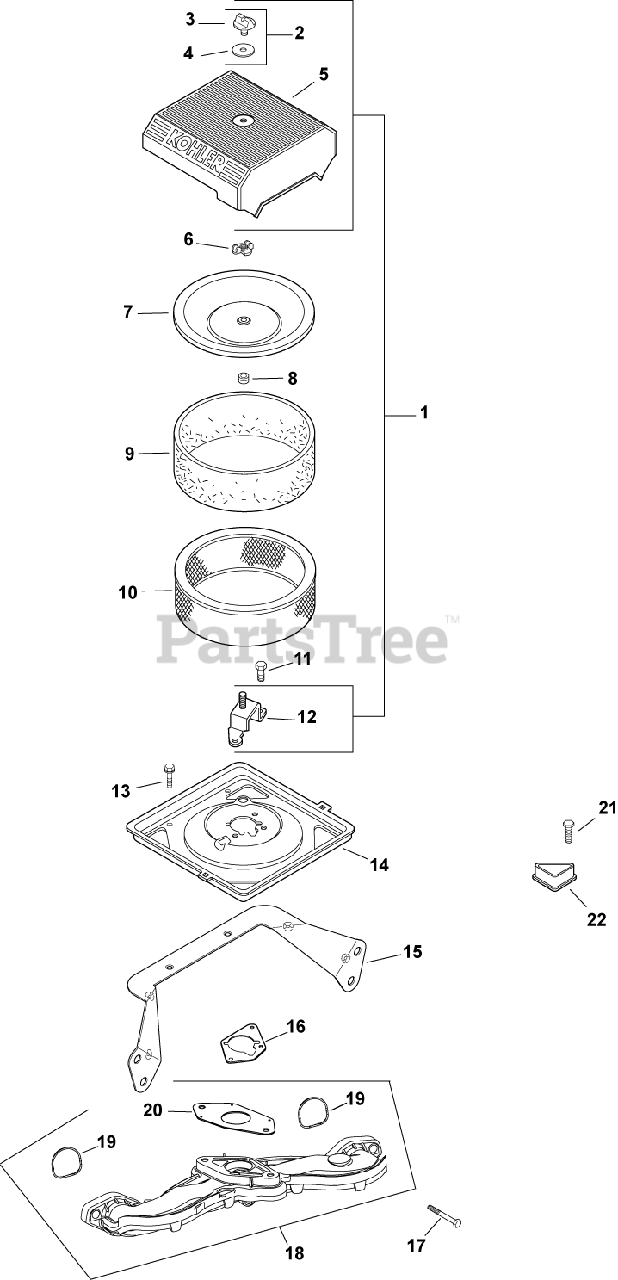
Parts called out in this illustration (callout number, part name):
1	KIT, AIR CLEANER COVER
2	KIT, KNOB W/SEAL
3	KNOB, COVER
5	COVER, AIR CLEANER
6	NUT, WING
7	COVER, INNER AIR CLEANER
8	SEAL, BREATHER
9	PRE-CLEANER (HIGH)
10	ELEMENT, AIR FILTER (HIGH) - Also available Retail Packaged 24 883 03-S1 Air Filter Kit
11	SCREW, FLG THD FRM M6X1.0X16
12	BRACKET, AIR CLEANER-USE 24 126 210-S
13	SCREW, FLG THD FRM M5X.8X10
14	BASE, AIR CLEANER -USE 24 094 88-S
15	BRACKET, AIR CLEANER BASE
16	GASKET, AIR CLEANER BASE
17	SCREW, FLG M6X1.0X40
18	MANIFOLD, INTAKE - PLASTIC-USE 24 164 93
19	O-RING, INTAKE PORT
20	GASKET, CARBURETOR
21	SCREW, WSH HD TAP #8-18X1/2"
22	COVER, BLOWER HOUSING USE 24 096 160-S
